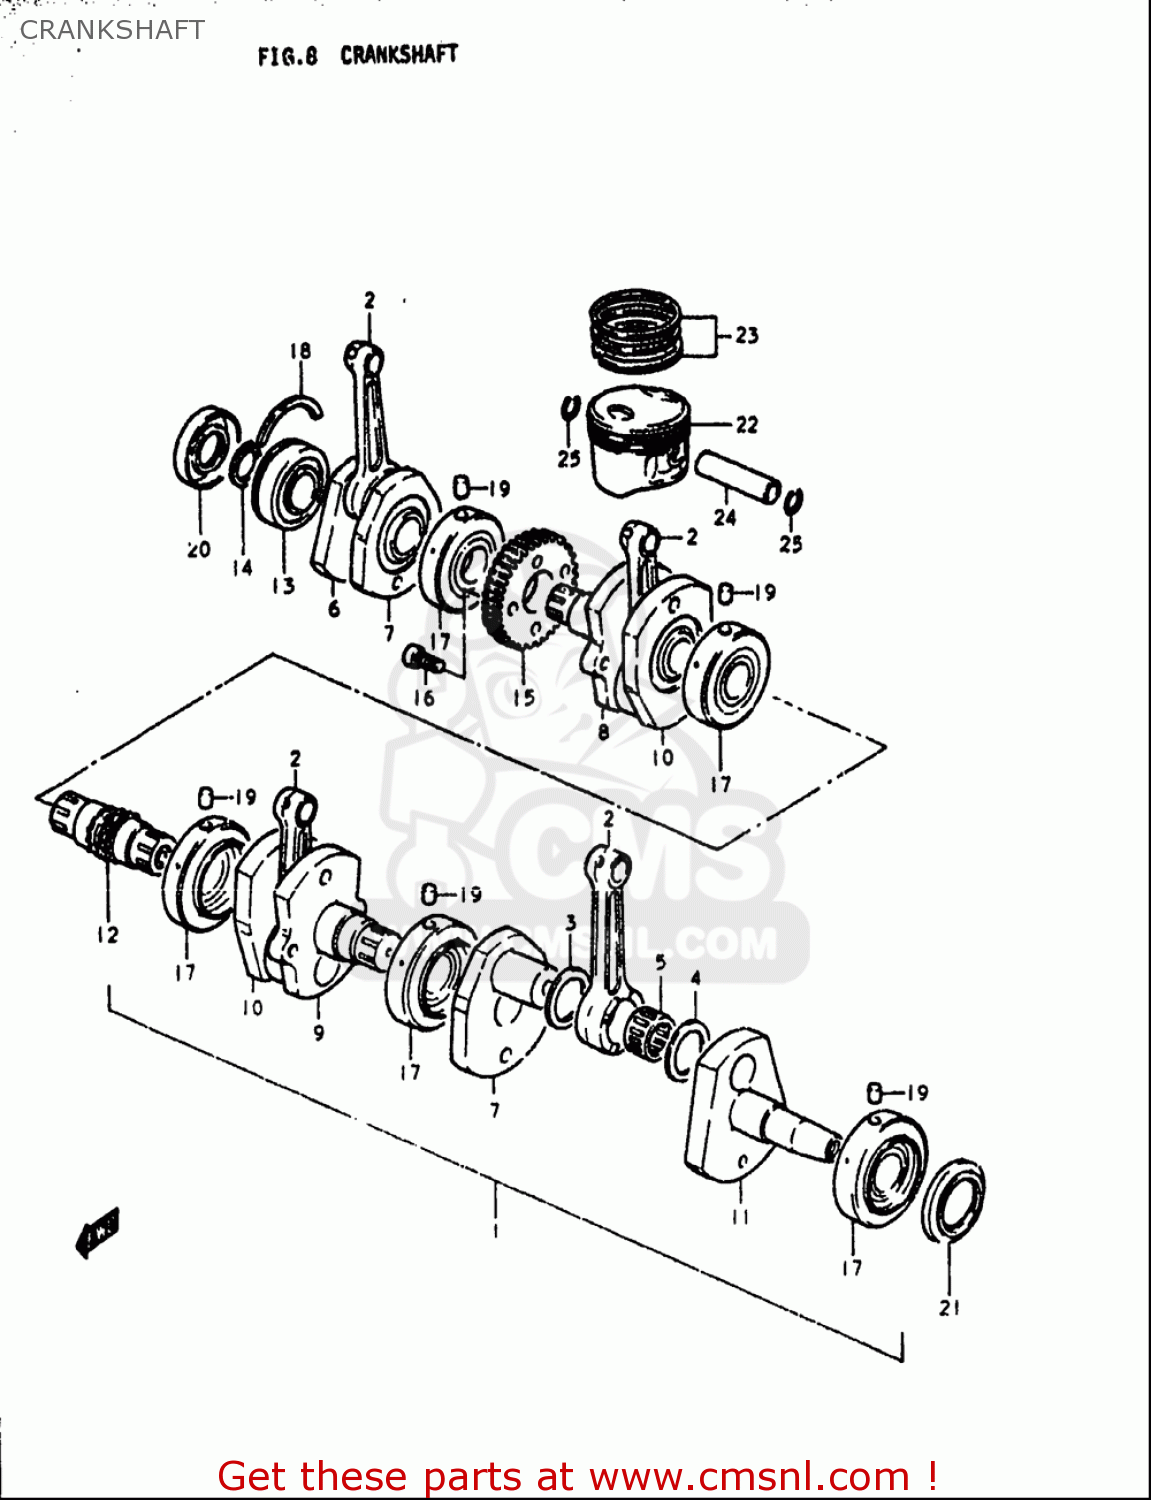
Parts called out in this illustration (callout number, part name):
2	ROD,CONNECTING
5	BEARING(29X39X20)
13	BEARING(30X72X19)
14	CIRCLIP
16	BOLT
17	BEARING(32X72X21)
18	C RING
19	PIN
20	SEAL,OIL(30X72X11)
21	SEAL,OIL(47.3X60X6.5)
22	PISTON
23	RING SET,PISTON
24	PIN,PISTON (18MM)
25	CIRCLIP,PISTON PIN
